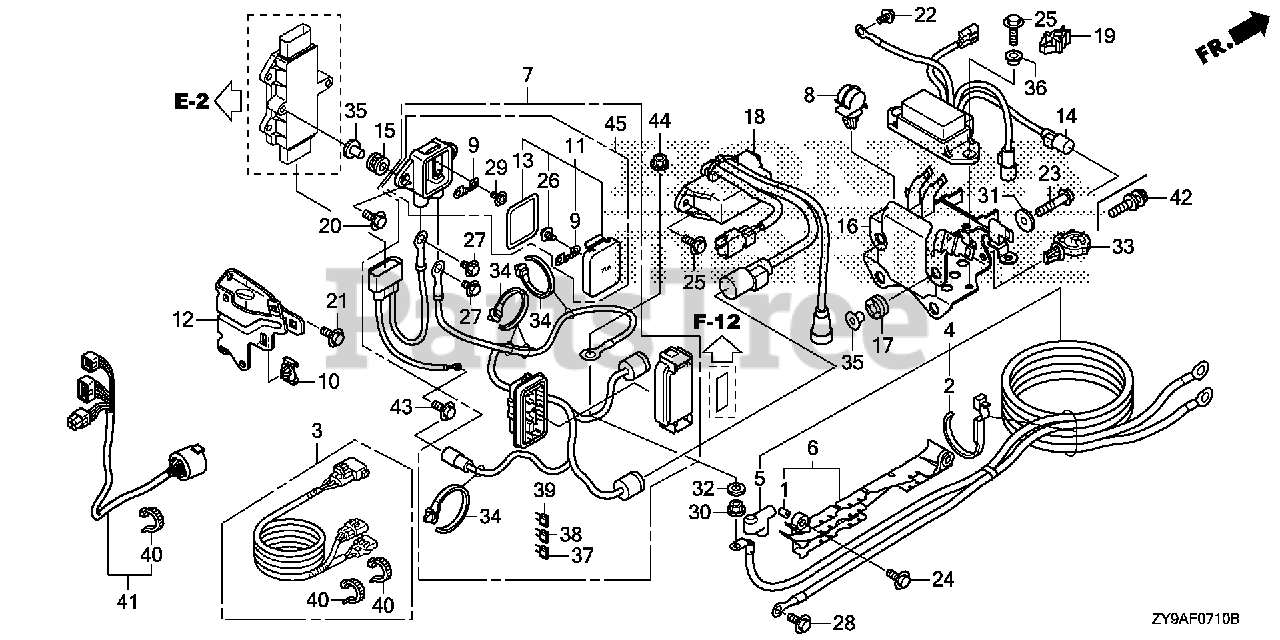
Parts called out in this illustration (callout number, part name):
1	COLLAR, DISTANCE (6.5X11X7.5)
2	BAND, WIRE
2	BAND, WIRE (165MM) (BLACK)
4	CABLE ASSY., STARTER
5	COVER, STARTER TERMINAL
6	HOLDER, STARTER CABLE
8	CLAMP, WIRE
10	CLIP, CONNECTOR HOLDER (B)
12	BRACKET, FUSE BOX
14	RELAY ASSY., POWER TILT
16	BRACKET, RELAY
17	GROMMET, RELAY BRACKET
18	RELAY ASSY., MAIN
19	CLIP, TUBE (3.5)
21	BOLT, FLANGE (6X14) (CT200)
22	BOLT, FLANGE (6X12)
24	BOLT, FLANGE (6X20)
25	BOLT, FLANGE (6X14)
28	BOLT, FLANGE (8X18)
30	NUT-WASHER (8MM)
32	WASHER, PLAIN (8MM)
33	CLIP, WIRE HARNESS (25MM)
35	COLLAR, MODULE IGNITION CONTROL CASE (CDI)
36	COLLAR, P.T.T. RELAY
42	BOLT-WASHER (6X27) (CT200)
